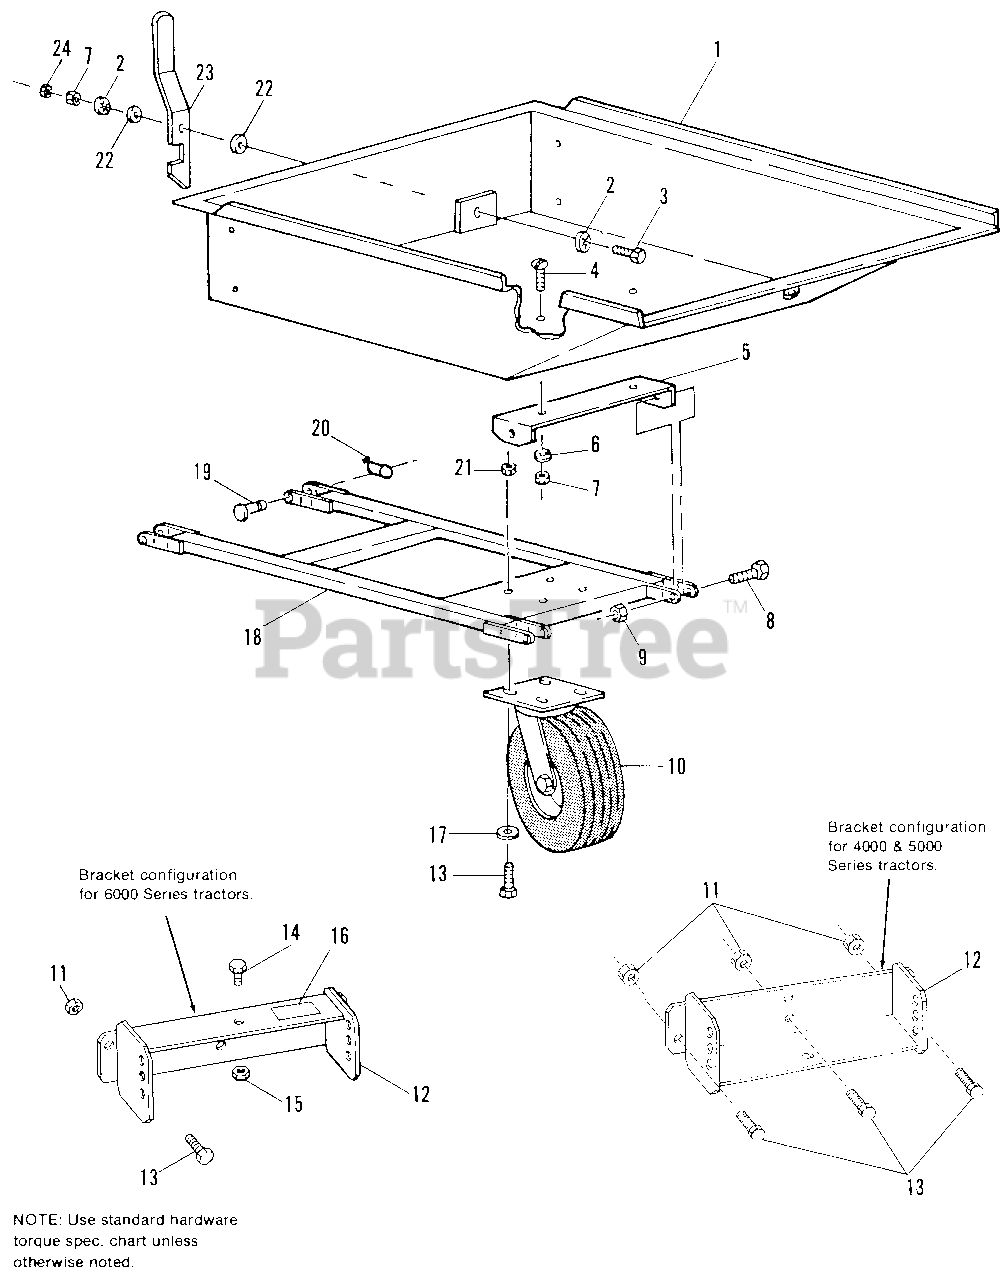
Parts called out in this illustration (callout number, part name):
1	BOX (Order 1691243 from wholegoods.)
2	WASHER, Spring, 5/16
3	CAPSCREW, Hex Hd., 5/16-18 x 1-1/4
4	BOLT, Slotted Truss Hd., 5/16-18 x 3/4
5	"S" BRACKET
6	LOCKWASHER, 5/16
7	NUT, Hex, 5/16-18
8	CAPSCREW, Hex Hd., 1/2-13 x 1-1/4
9	NUT, Hex Lock, 1/2-13
10	WHEEL, Sewivel
11	NUT, Hex Lock 3/8-16
12	BRACKET, Hitch
13	CAPSCREW, Hex, 3/8-16 x 1
14	CAPSCREW, Hex, 3/8-16 x 3/4 (6000 Series Tractors Only)
15	NUT, Hex Full Lock, 3/8-16
16	DECAL, Warning (6000 Series Only)
17	FLATWASHER, 3/8 S.A.E.
19	PIN, Clevis, 1/2 x 1-1/4
20	COTTER, Hairpin
21	NUT, Hex Lock, 3/8-16
22	FLATWASHER, 5/16
23	HANDLE, Latch
24	NUT, Hex, Jam, 5/16-18
